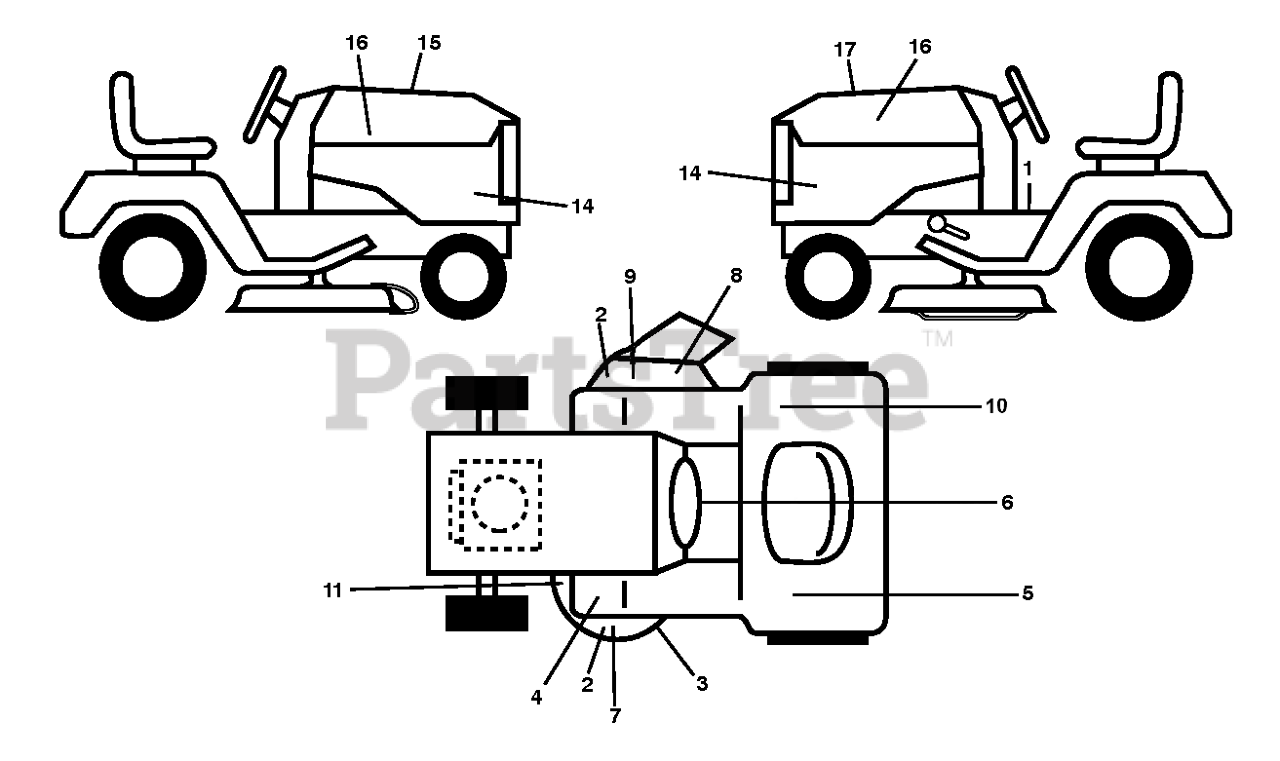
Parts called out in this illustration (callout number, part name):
1	DECAL.FENDER.WARNING.ENGLISH
1	DECAL.WARNING.2007.ENG/FR
1	DECAL.TRACTOR.SADDLE
2	DECAL.DECK.CLEARCUT.NOSTEP
3	DECAL DECK DECAL DECAL.DECK.WA
4	DECAL BELT ROUTING DECAL DECAL
5	DECAL.DECK.BUILTINAMERICA.HUSQ
5	Decals
5	DECAL.RESERVEFUELSELCTR.ENG
6	DECALS.WARN.CA.SPKARREST/PROP
7	DECAL.54DECK.CLEARCUT.VER2.18
7	DECAL DECK DECAL DECAL.54DECK.
8	DECAL.TRACT/ZTR.DECKWARN.HUSQ
9	DECAL BELT ROUTING DECAL DECAL
10	DECAL CERTIFICATION DECAL EMCC
11	DECAL DECK DECAL DECAL.DECK.WA
14	DECAL TRACTOR SIDE PANEL DECAL
15	DECAL.WARNING.CUST.RESP.E85.
16	DECAL.BADGE.170MM.TEXTLOGO.
17	DECAL.RPL.KW.FR7.TLB.54F
17	DECAL
